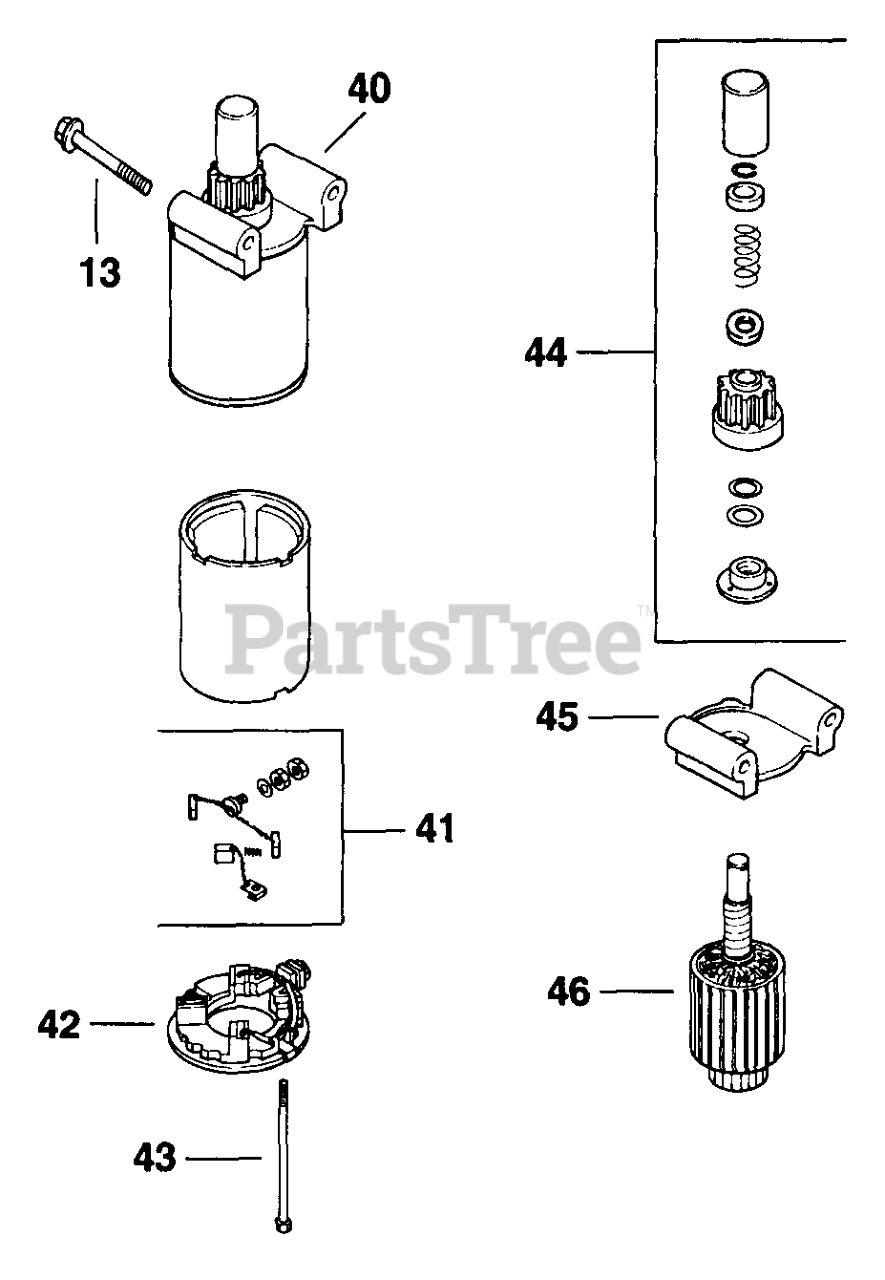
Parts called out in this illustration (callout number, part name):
41	Kit, Brush And Spring
42	Cap, Commutator End
43	Screw, Hex. Flange 1/4-20x4-5/8"
44	Kit, Drive
45	Cap, Drive End
46	Armature
